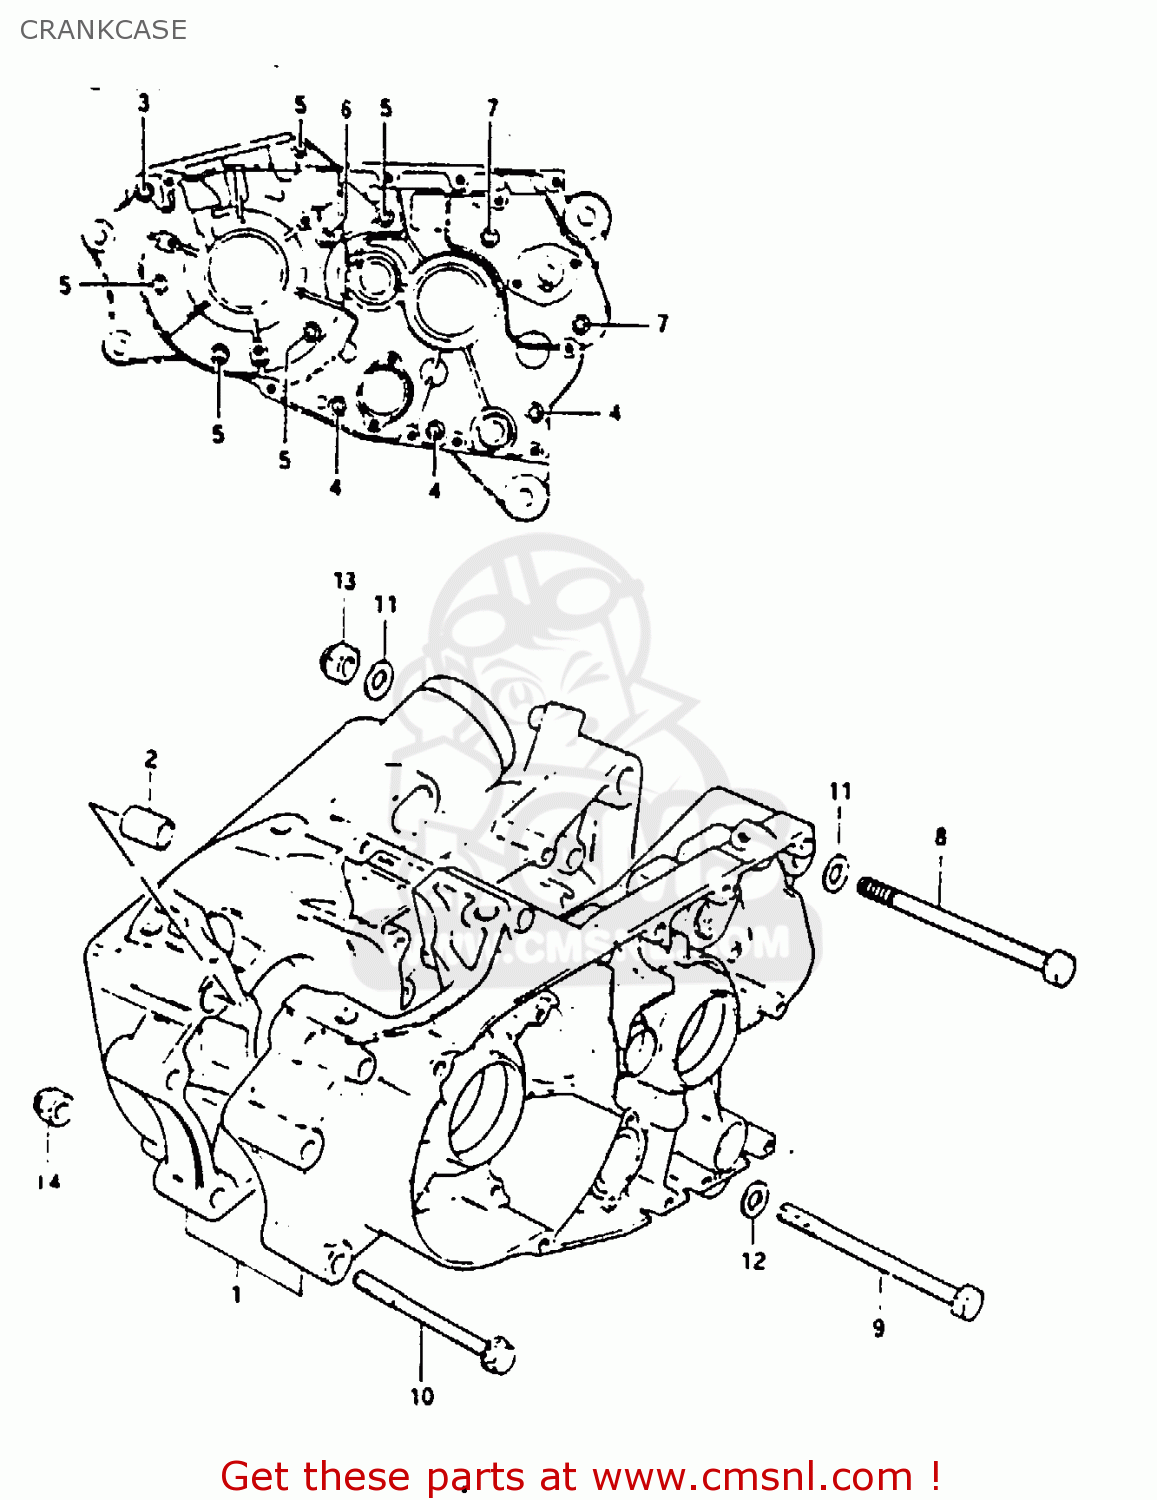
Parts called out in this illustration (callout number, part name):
1	CRANKCASE SET
2	PIN
3	SCREW 6X70
4	SCREW 6X65
5	SCREW
6	SCREW
7	SCREW
8	BOLT 10X120
9	BOLT 10X115
10	BOLT 8X90
11	WASHER
12	WASHER(10.5X20X3.2)
13	NUT
14	NUT
